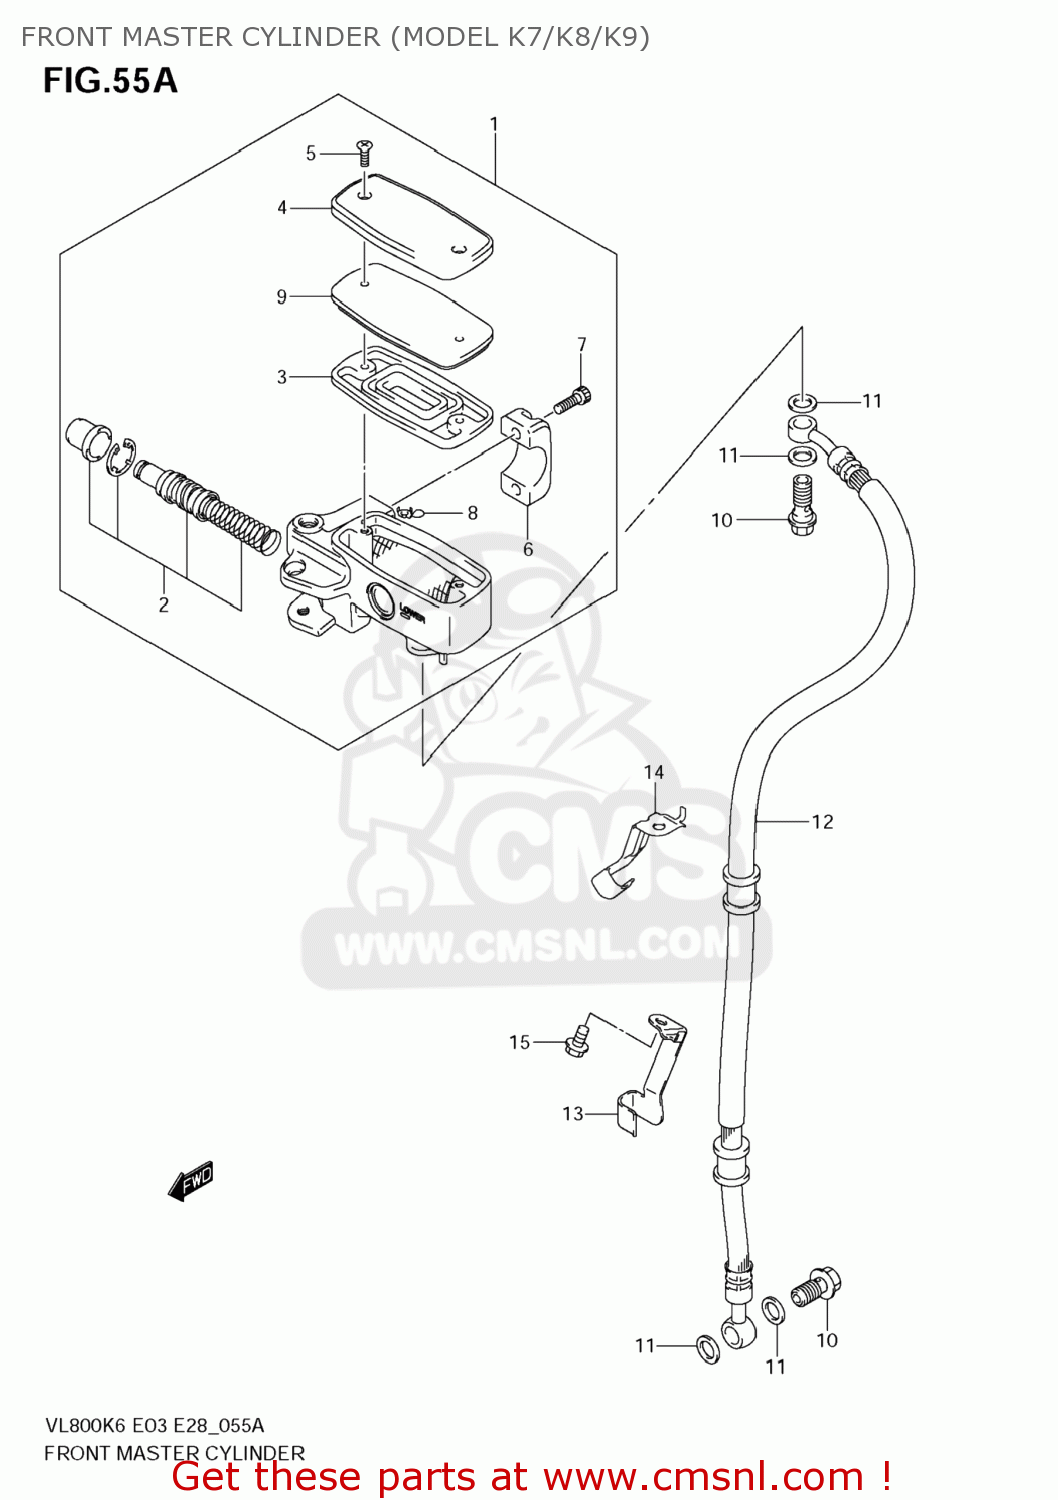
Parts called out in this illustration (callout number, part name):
1	CYLINDER ASSY,FR MASTER
2	PISTON/CUP SET
3	DIAPHRAGM
4	CAP
5	SCREW
6	HOLDER
7	BOLT
8	PROTECTOR
9	PLATE,DIAPHRAGM
10	BOLT UNION
11	WASHER(10X15X1.5)
12	HOSE,FR BRAKE
13	CLAMP,FR BRAKE HOSE UPR
14	CLAMP,FR BRAKE HOSE UPR
15	BOLT
